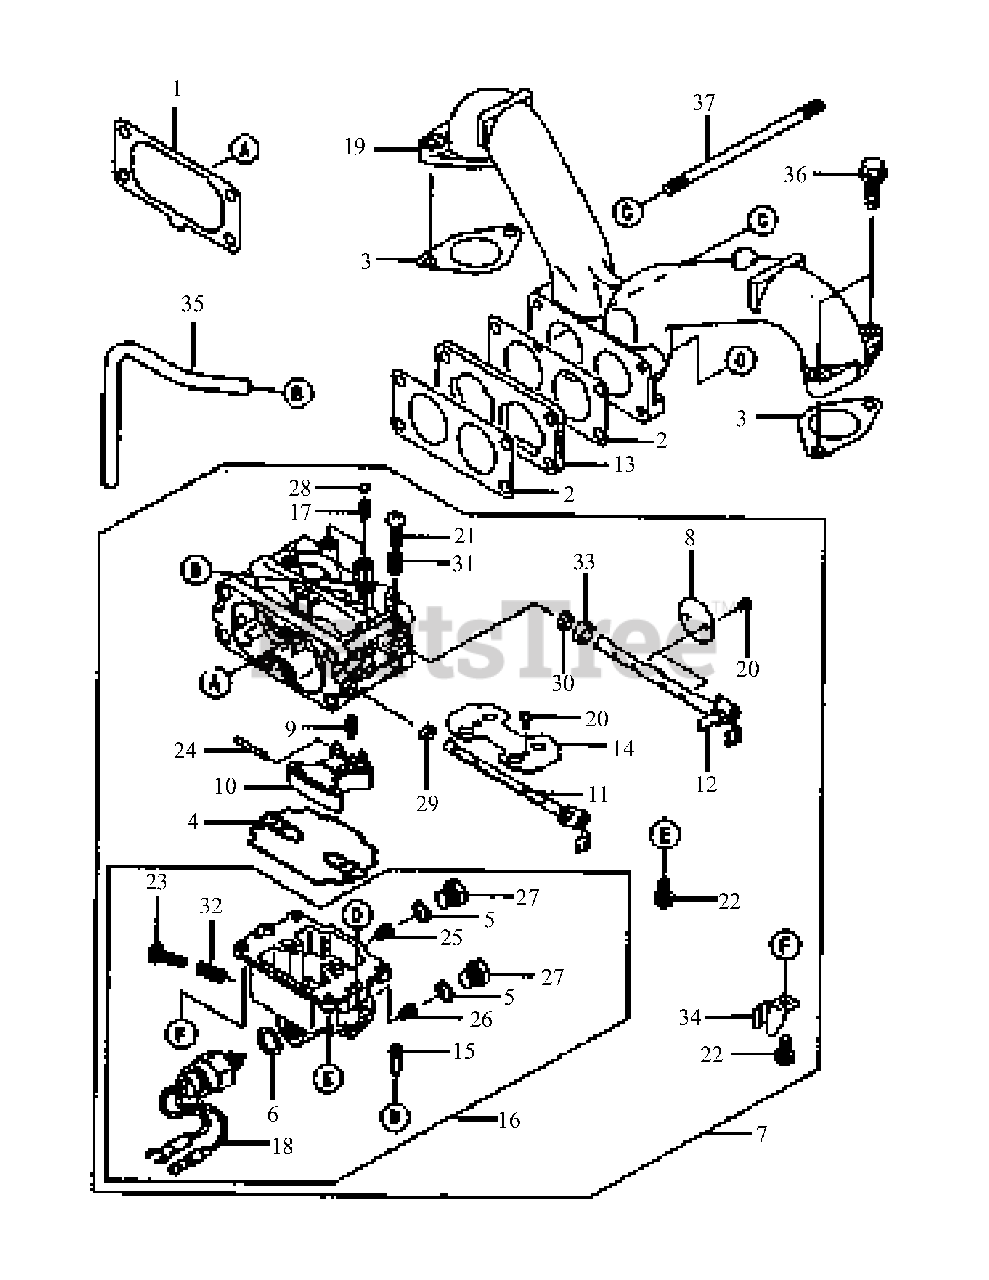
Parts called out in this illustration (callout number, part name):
1	Gasket, Air Filter
2	Gasket, Carburetor
4	Gasket,Float Chamber
5	Gasket,Main Plug
6	Gasket, Solenoid
7	Carburetor Assembly
8	Valve-Throttle
11	Shaft-Choke
12	Shaft-Throttle
16	Chamber-Float
19	Manifold, Intake
25	Jet-Main #104
26	Jet-Main #106
27	Plug,Main Jet
28	Plug, Expansion
35	Tube 4.76x7.94x160
